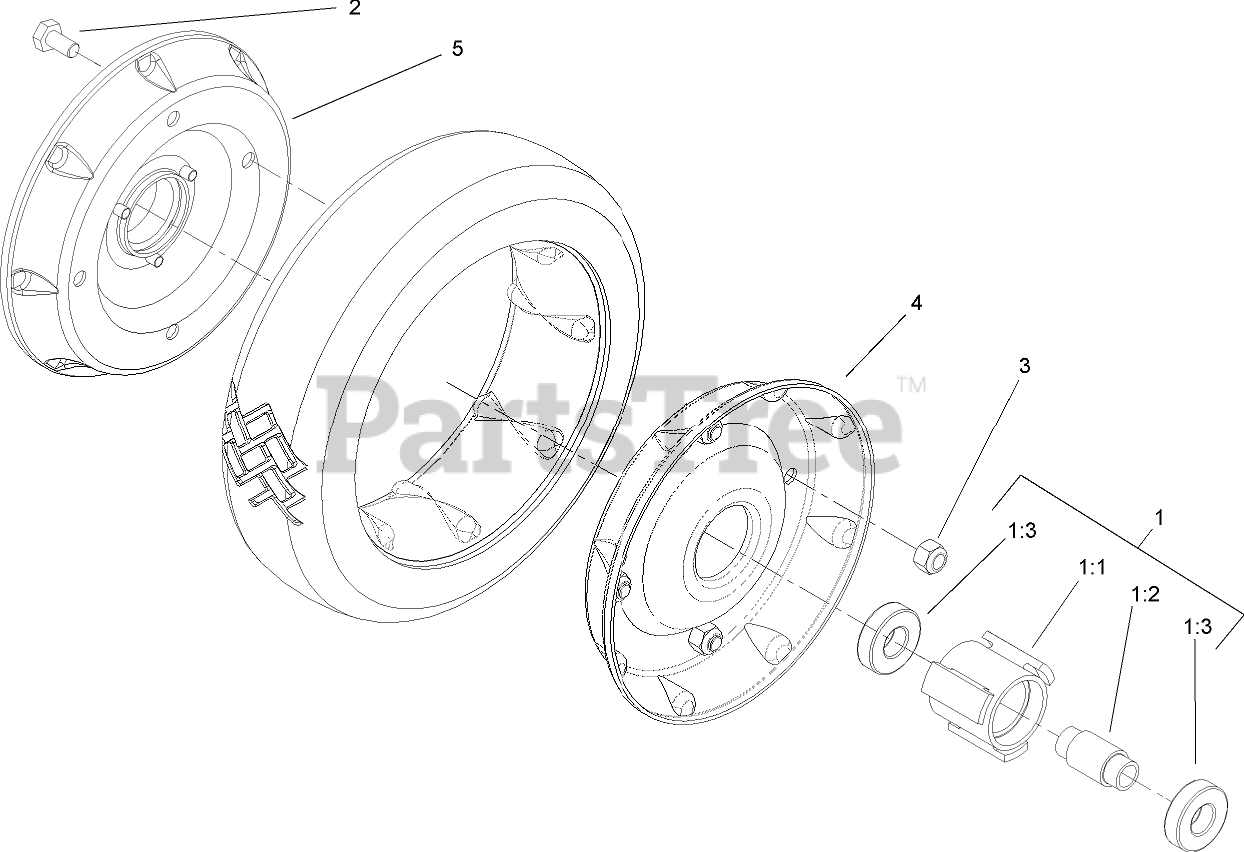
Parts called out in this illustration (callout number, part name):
1	HUB and BEARING ASM
1:1	HUB-BEARING
1:2	SPACER-BEARING
1:3	BEARING-WHEEL
2	SCREW-HH
3	NUT-LOCK, NI
4	PLATE-WHEEL, HALF
5	WHEEL HALF AND GEAR ASM
